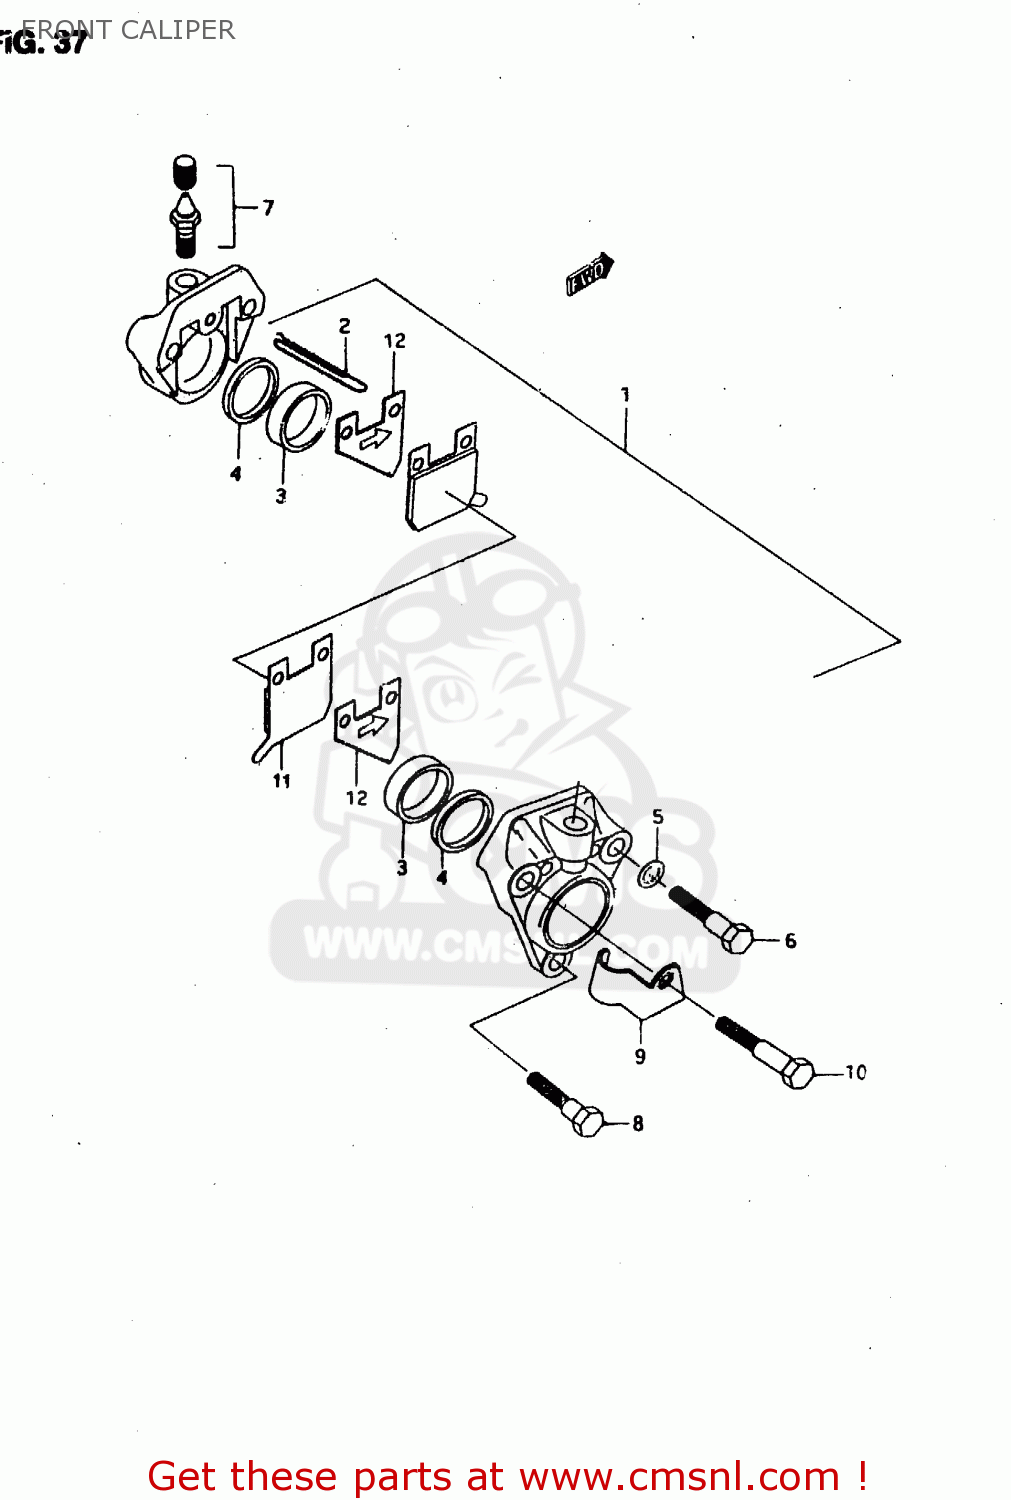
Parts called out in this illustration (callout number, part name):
1	CYLINDER ASSY, FRONT MASTER
2	SPRING,PAD
3	PISTON
4	OIL SEAL
5	WASHER
6	BOLT
7	BLEEDER
8	BOLT
9	BRACKET
10	BOLT
11	PAD SET
12	SHIM,PAD
